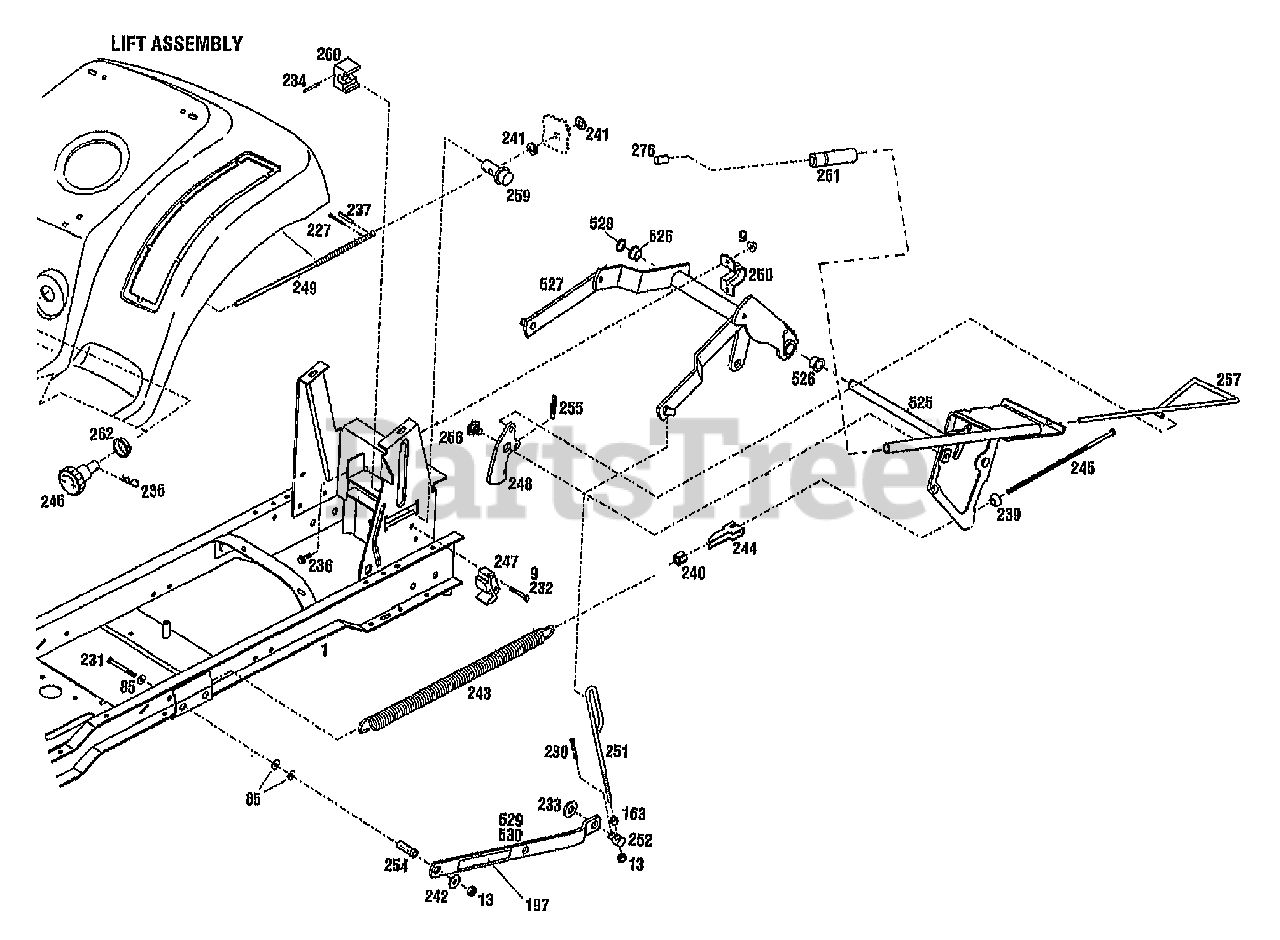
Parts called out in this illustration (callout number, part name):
1	ASSM-FRAME LTX
9	NUT-HFLK 5/16-18 ZP
13	NUT-LOCK 3/8-16
85	WASHER-FLAT 3/8 SAE
163	NUT-HEX 3/8-16 ZP
197	DECAL-WARNING
227	PIN-COTTER .125 X .75 ZP
230	PIN-COTTER .120X1.25 ZP
231	SCR-HH 3/8-16X3.0 G5 ZP
232	SCR-HH 5/16-18X1.5 G5 ZP
233	WASHER-1.305X.649X.098 ZP
234	PIN-DRIVE
235	PIN-HITCH
236	SCR-HFLK 5/16-18X.75 ZP
237	PIN-ROLL .156X1.0
239	BEARING-SPHERICAL
240	NUT-SPECIAL 5/16-18
242	WASHER-1.5X.375X.18 ZP
243	SPRING-LIFT ASSIST
244	BRKT-LIFT ASSIST
245	SCR-LIFT ASSIST
246	KNOB-HEIGHT ADJUST
247	BLOCK-DETENT
249	KIT-SVC SCR HGT ADJ
250	CLAMP-LIFT
252	SWIVEL-LIFT REAR
254	SPACER
256	SCR-SHOULDER
259	BLOCK-HEIGHT ADJUST
260	COLLAR-HEIGHT ADJUST
261	GRIP-LIFT
262	GROMMET-SNAP BUSHING
276	BUTTON-LIFT
525	HANDLE-LIFT
528	RING-RETAINING EXT .694 ID
529	LINK-LIFT W/DECAL
530	LINK-LIFT W/DECAL
